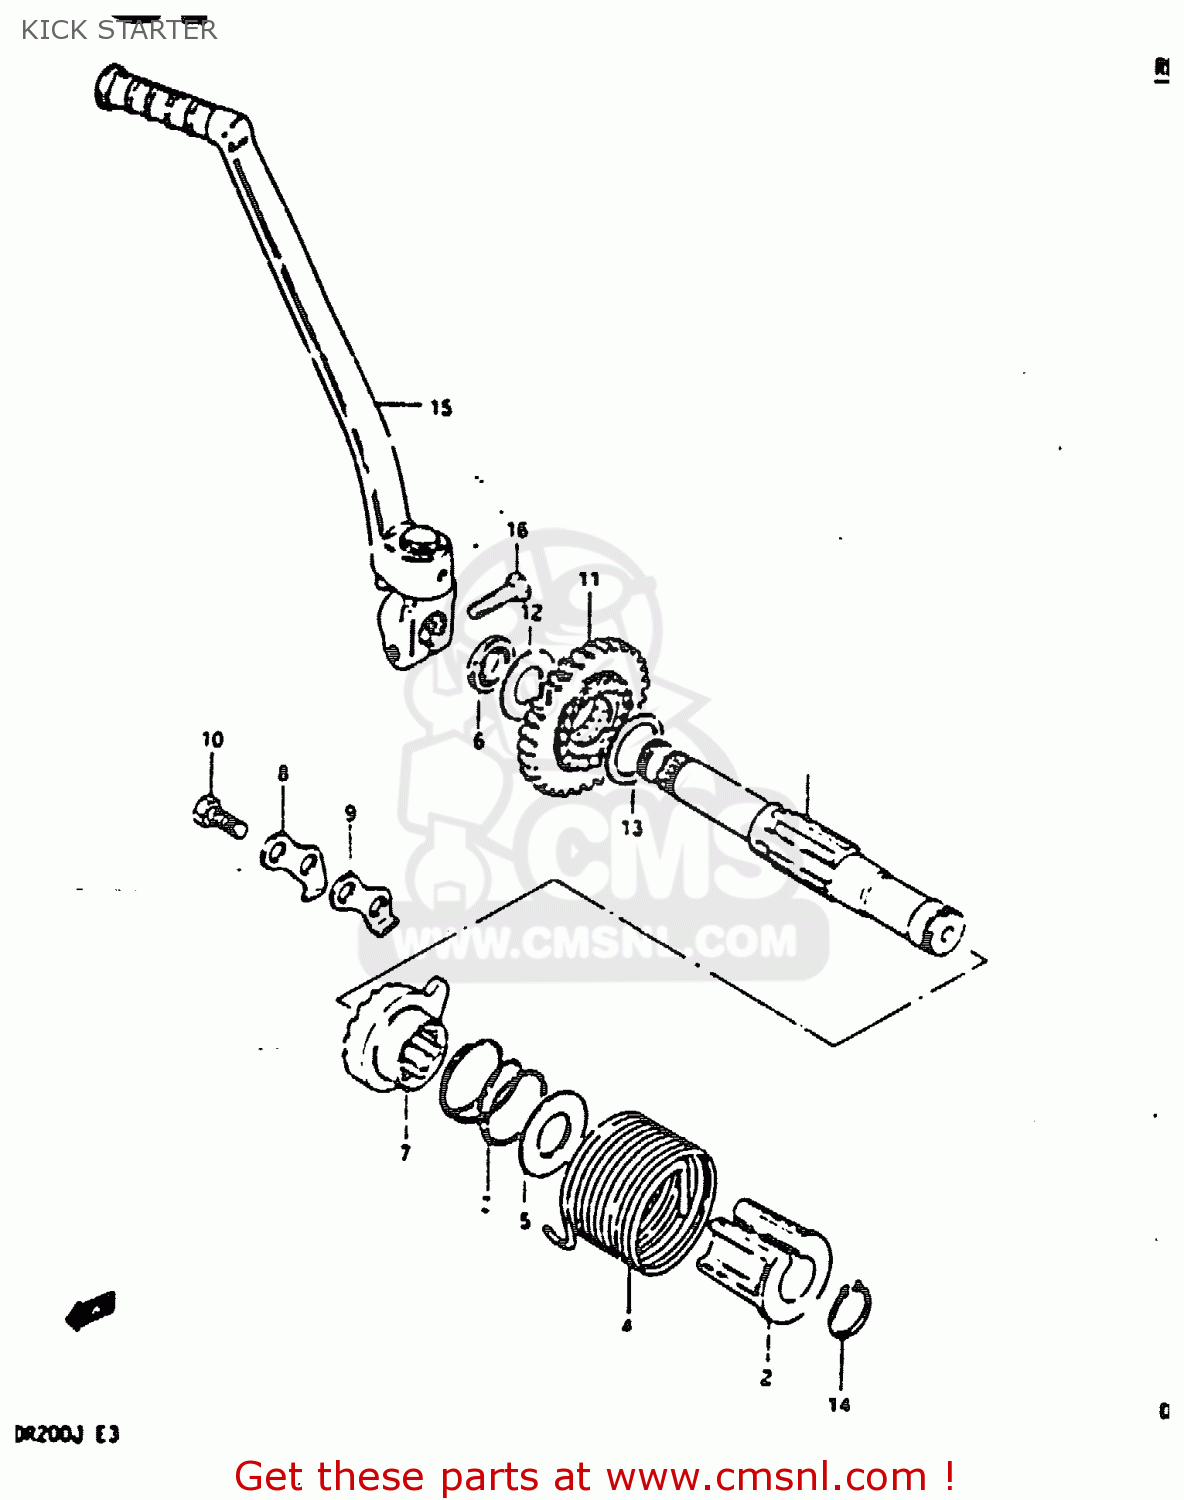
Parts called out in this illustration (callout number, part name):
1	SHAFT,KICK STARTER
2	GUIDE,KICK STARTER SFT SPRING
3	SPRING
4	SPRING
5	WASHER
6	SEAL,OIL(16X24X5)
7	STARTER,KICK
8	GUIDE,KICK STARTER
9	STOPPER,KICK STARTER
10	BOLT
11	GEAR,KICK STARTER DRIVE
12	WASHER(16X30X1)
13	WASHER
14	CIRCLIP
15	LEVER ASSY,KICK STARTER
16	BOLT 8X25
